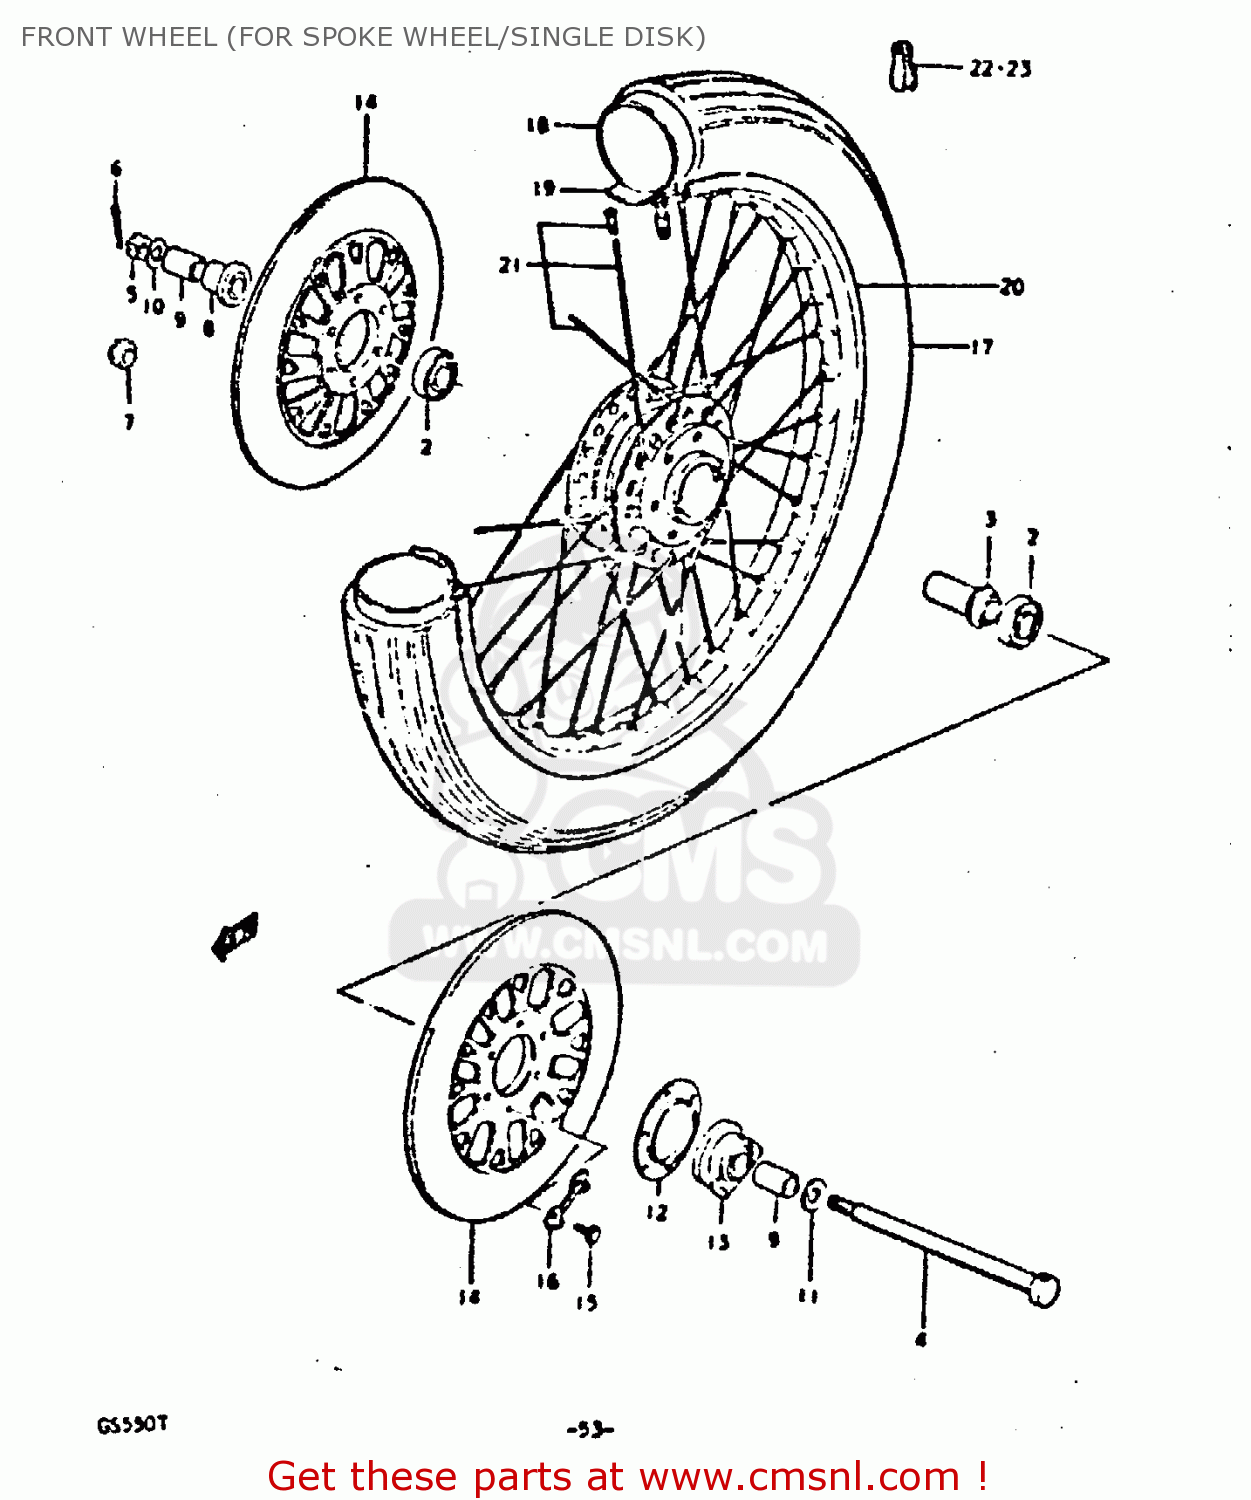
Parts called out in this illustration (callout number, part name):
1	DRUM,FRONT HUB
2	BEARING
3	SPACER,FR HUB BEARING
4	AXLE,FRONT
5	NUT 12MM
6	COTTER PIN
8	SPACER,FR AXLE,R
9	SPACER(15X22X30)
10	WASHER
12	COVER, LH
13	BOX ASSEMBLY,SPEEDOMETER GEAR
14	DISC,FR BRAKE
15	BOLT(8X25)
16	WASHER
17	TIRE,FRONT
18	TUBE,INNER
19	PROTECTOR,WHL INR TUBE
20	RIM,FR WHEEL
21	SPOKE SET,FRONT
22	BALANCER,WHEEL (B)
23	BALANCER,WHEEL (30G)
